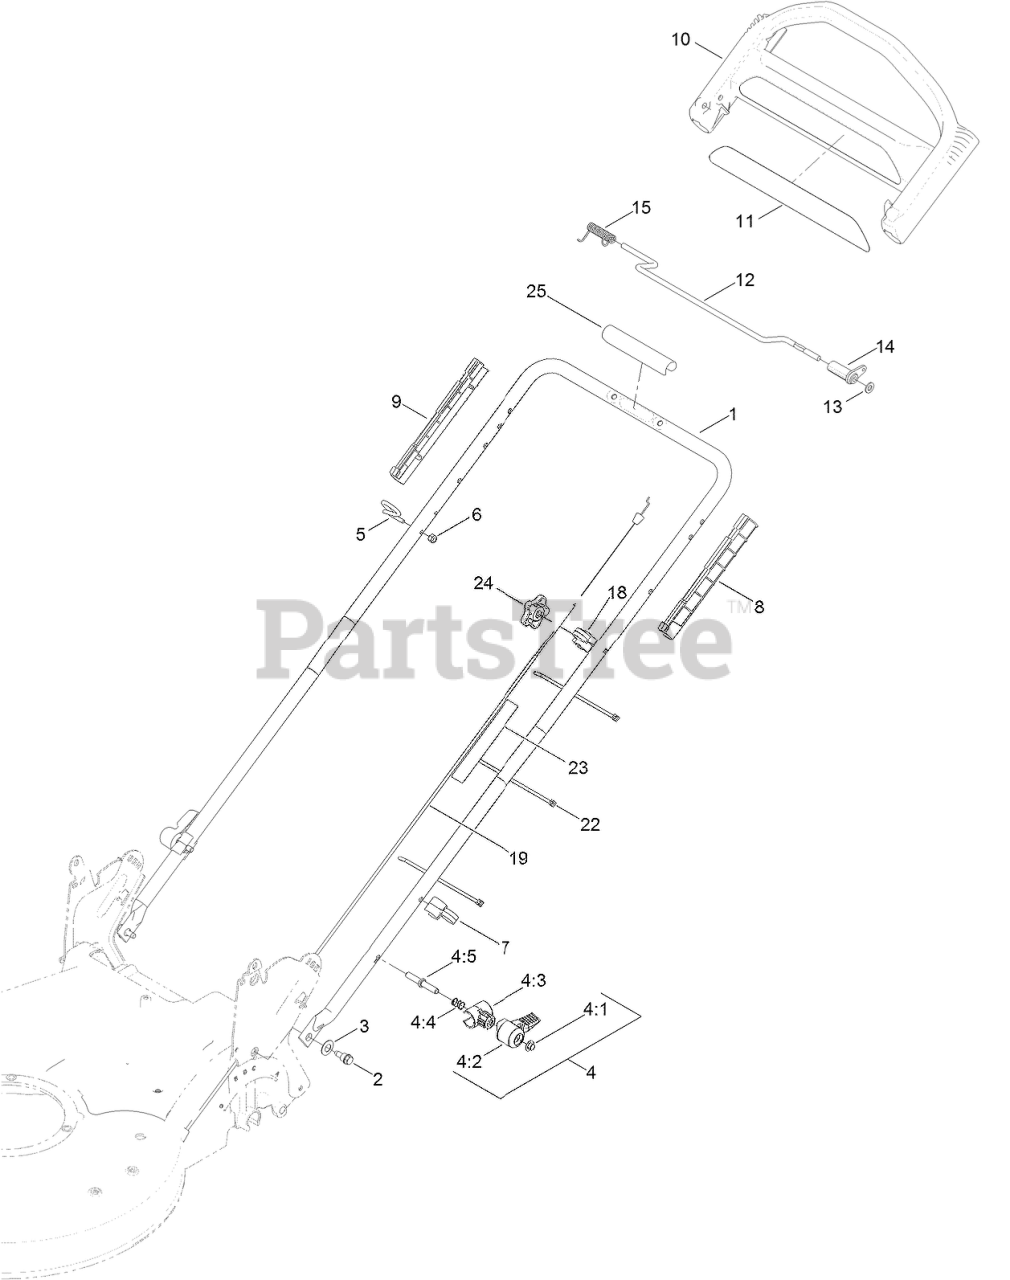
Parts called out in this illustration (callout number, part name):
2	BOLT-SHOULDER
3	WASHER-SPRING, CONICAL
4	QUICK RELEASE ASM
4:1	NUT-PUSH
4:2	LEVER
4:3	ANCHOR-SPRING
4:4	SPRING-COMPRESSION
4:5	ROD-RELEASE
5	GUIDE-ROPE
6	NUT-LOCK, NI
7	GUIDE-CABLE
8	GUIDE-LH
9	GUIDE-RH
10	HANDLE-CONTROL
12	BAR-CONTROL, TRACTION
13	WASHER-PLAIN
14	LEVER-TRACTION
15	Spring-Torsion
18	ANCHOR-CABLE
19	CABLE-TRACTION
22	TIE-CABLE
23	DECAL-TRACTION, ADJUST
24	KNOB-HANDLE, LOCKING
25	HANDLE-COVER
